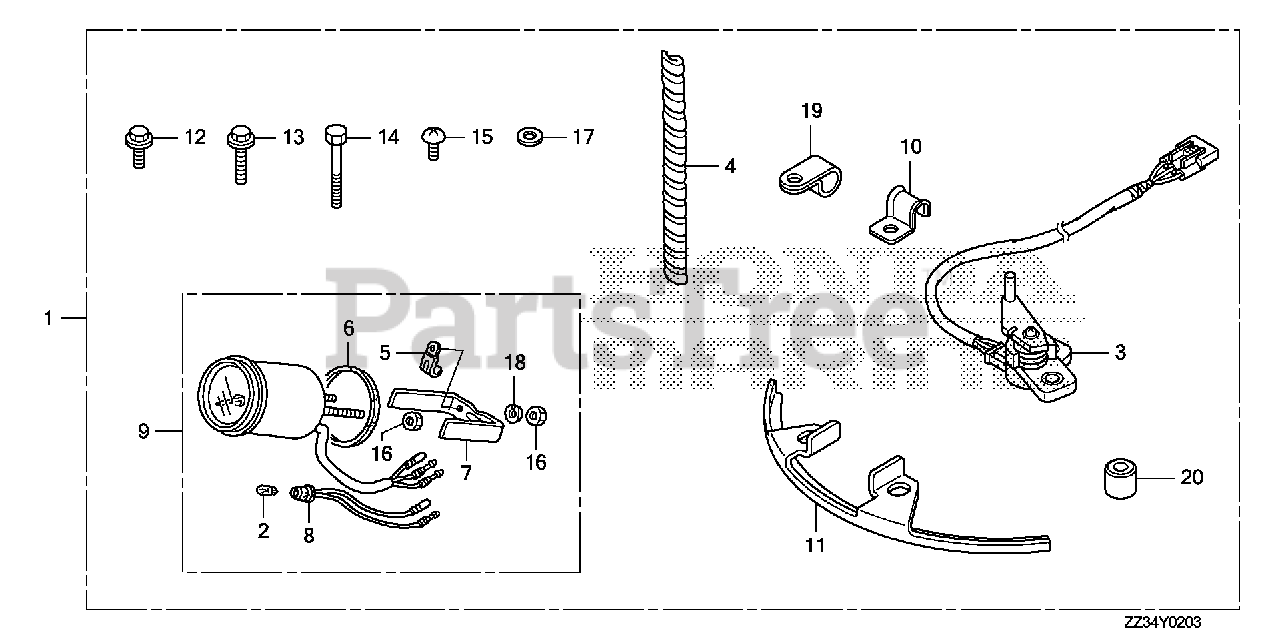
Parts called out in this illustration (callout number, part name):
1	METER KIT, RUDDER (WHITE)
1	METER KIT, RUDDER (BLACK)
2	BULB, WEDGE BASE (12V 1.7W)
3	SENSOR ASSY., RUDDER
4	TUBE, SPIRAL
5	CLAMP
6	GASKET
7	BRACKET
8	SOCKET
9	METER ASSY., RUDDER (BLACK)
10	CLAMP, TUBE
11	PLATE, STEERING ANGLE SENSOR
12	BOLT, FLANGE (6X12)
13	BOLT, FLANGE (6X20)
14	BOLT, HEX. (6X35)
15	SCREW, PAN (6X8)
16	NUT, HEX. (4MM)
17	WASHER, PLAIN (6MM)
18	WASHER, SPRING (4MM)
19	CLIP (14MM)
20	COLLAR, DISTANCE (6.5X16X14.5)
